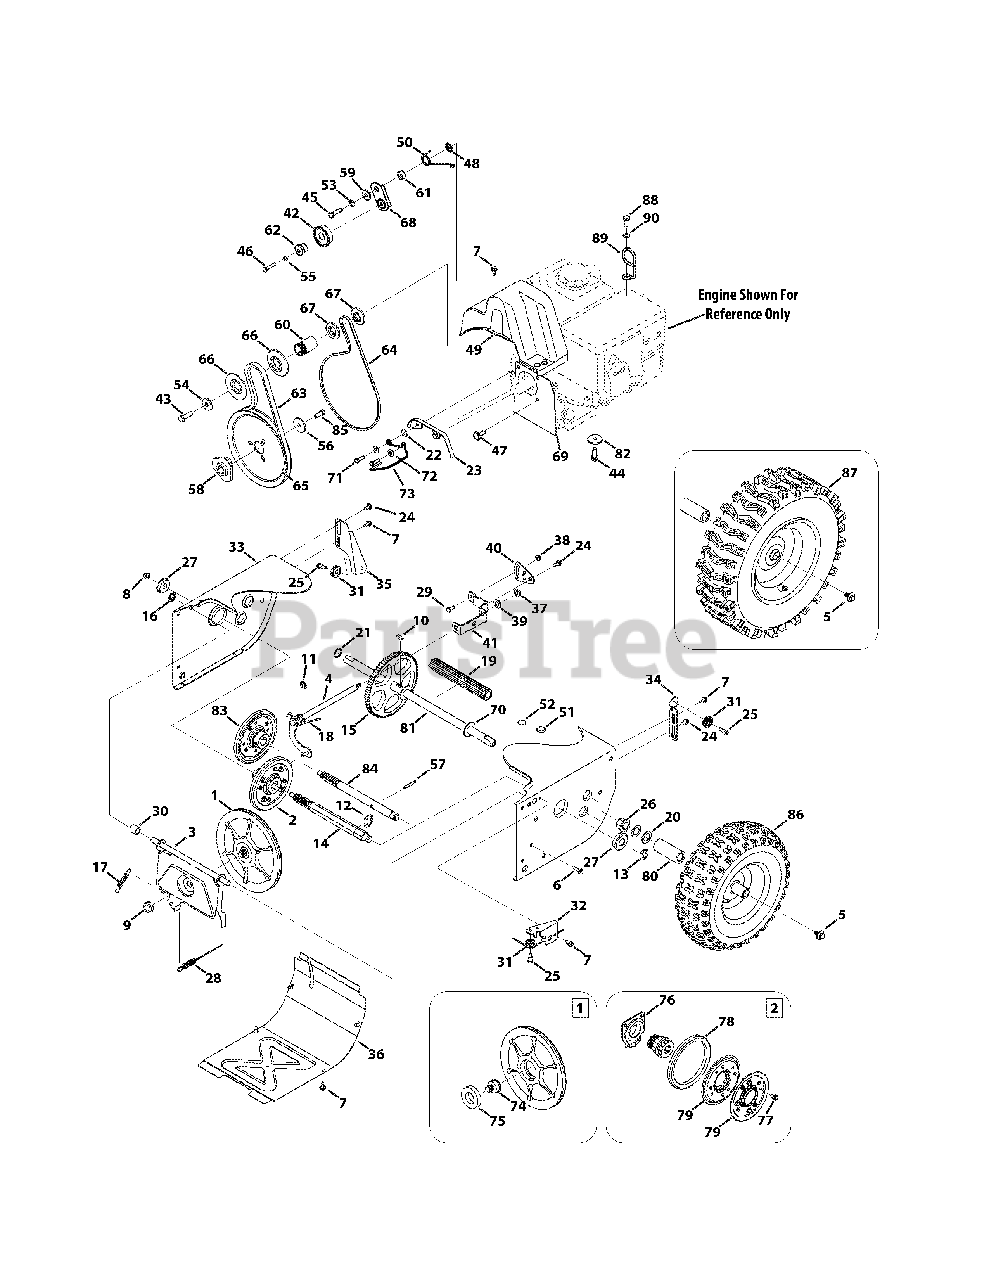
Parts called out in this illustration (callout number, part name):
1	Disc Assembly, Friction Wheel
2	Friction Wheel Assembly, 5.5 OD
3	Friction Wheel Support Bracket
4	Rod Shift Assembly
5	Screw, 5/16-24 x .750
6	Taptite Screw, 1/4-20 x 1.000
7	Taptite Screw, 1/4-20 x .625
8	Flange Lock Nut, 3/8-16
9	Flange Nut, 5/8-18
10	Hi-pro Key, 3/16 x 3/4 Dia.
11	E-Ring
12	Retaining E-Ring, .875 Dia.
13	E-Ring, .750 Dia.
14	Hex Shaft, 7-Tooth
15	Gear, 80-Tooth
16	Speed Nut, .500
17	Extension Spring
18	Torsion Spring, .750 x .968
19	Axle Spacer
20	Flat Washer, .793 x 1.24 x .060
21	Flat Washer, .75 x 1.00 x .060
22	Washer, Flat, .330 x .687 x .030
23	Belt Cover
24	Shoulder Screw, .368 x .113, 1/4-20
25	Shoulder Screw, 1/4-28, .340 x .355
26	Hex Flange Bearing
27	Ball Bearing, 17 x 40 x 12
28	Wheel Clutch Cable, 44.955"
29	Hex Head Screw, 1/4-20 x .620
30	Spacer, .508 ID x .75 OD x .68
31	Cable Roller
32	Auger Cable Front Guide Bracket
33	Frame
34	Auger Cable Guide Bracket
35	Drive Cable Guide Bracket
36	Frame Cover
37	Flange Lock Nut, 5/16-18
38	Flange Lock Nut, 1/4-20
39	Washer, Flat, .469 x .875 x .105
40	Speed Selector Pivot Bracket
41	Speed Selector Shift Bracket
42	Idler Pulley Assembly
43	Hex Screw, 3/8-24 x 1.25
44	Sems Screw, 3/8-16 x 1.00
45	Hex Screw, 5/16-24 x 1.25
46	Hex Screw, 1/4-20 x 1.25
47	Shoulder Screw, 5/16-24 x .5
48	Push-on Nut, .25 Dia.
49	Belt Cover, 4-Way
50	Torsion Spring, .850 ID x .333
51	Plug, 3/8 ID
52	Plug, 1/2 ID
53	Lock Washer, 5/16
54	Flat Washer, .45 x 1.5 x .172
55	Washer, Lock, 1/4
56	Flat Washer, .34 x 1.50 x .150
57	Pin, Spirol, 2.5"
58	Adapter Pulley, .75 Dia.
59	Shoulder Spacer, .3175 x .5 x .0975
60	Spacer, .875 ID x 1.185 OD
61	Spacer, .340 x .750 x .330
62	Shoulder Space, .260 x .785 x .538
63	Auger Drive Belt, Standard
64	Wheel Drive Belt, Standard
65	Auger Drive Pulley, 8.1 x .5
66	Pulley Half, 2.600 OD
67	Pulley Half, 3/8 x 1.716 OD
68	Wheel Drive Idler Bracket
69	Cover Plate, Standard
70	Washer, Flat, .760 x 1.49 x .060
71	Hex Head Screw, 5/16-24 x 1.00
72	Washer, Flat, .349 x .879
73	Belt Guide
74	Friction Disc Bearing Pin
75	Ball Bearing, 30 x 55 x 13
76	Bearing Assembly
77	Taptite Screw, 5/16-18 x .750
78	Friction Wheel Rubber
79	Friction Wheel Plate
80	Spacer, 1.25 x .75 x 3.0
81	Axle, .75 x 22
82	Washer, Flat, .38 x 1.38 x .125
83	Friction Wheel Ass’y, Single-Speed
84	Shaft, Single-Speed
85	Hex Cap Screw, 5/16-24 x .875
86	Snow Hog Wheel, 13 x 4 x 6
87	X-Trac Wheel, 13 x 4 x 6, LH
88	Hex Head Screw, 1.25 x 20
89	Cable Guide
90	Washer, Flat, .330 x .630
